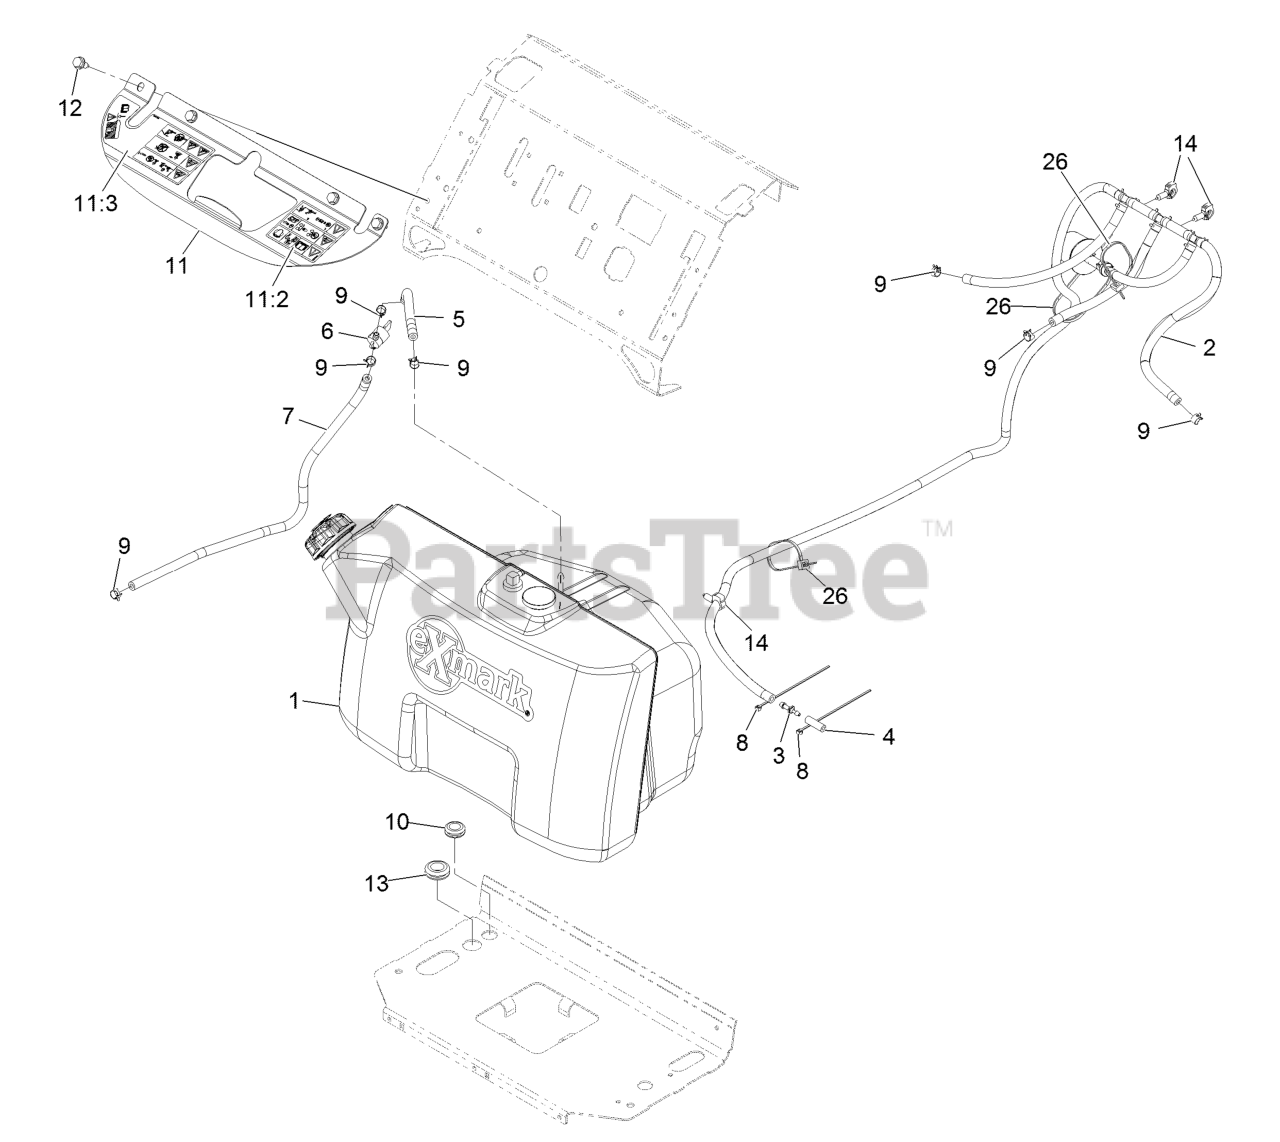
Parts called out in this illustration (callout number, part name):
2	VENT ASM
3	FITTING-STRAIGHT
4	HOSE-FUEL
5	HOSE-FUEL
6	VALVE-FUEL
7	HOSE-FUEL
8	TIE-CABLE
9	CLAMP-HOSE
10	GROMMET
11	BRACKET-TANK
11:2	DECAL-WARNING LH
11:3	DECAL-WARNING RH
12	Screw-HWH 5/16-18 X 3/4 Tf
13	GROMMET
14	CLIP-HARNESS
26	TIE-CABLE
